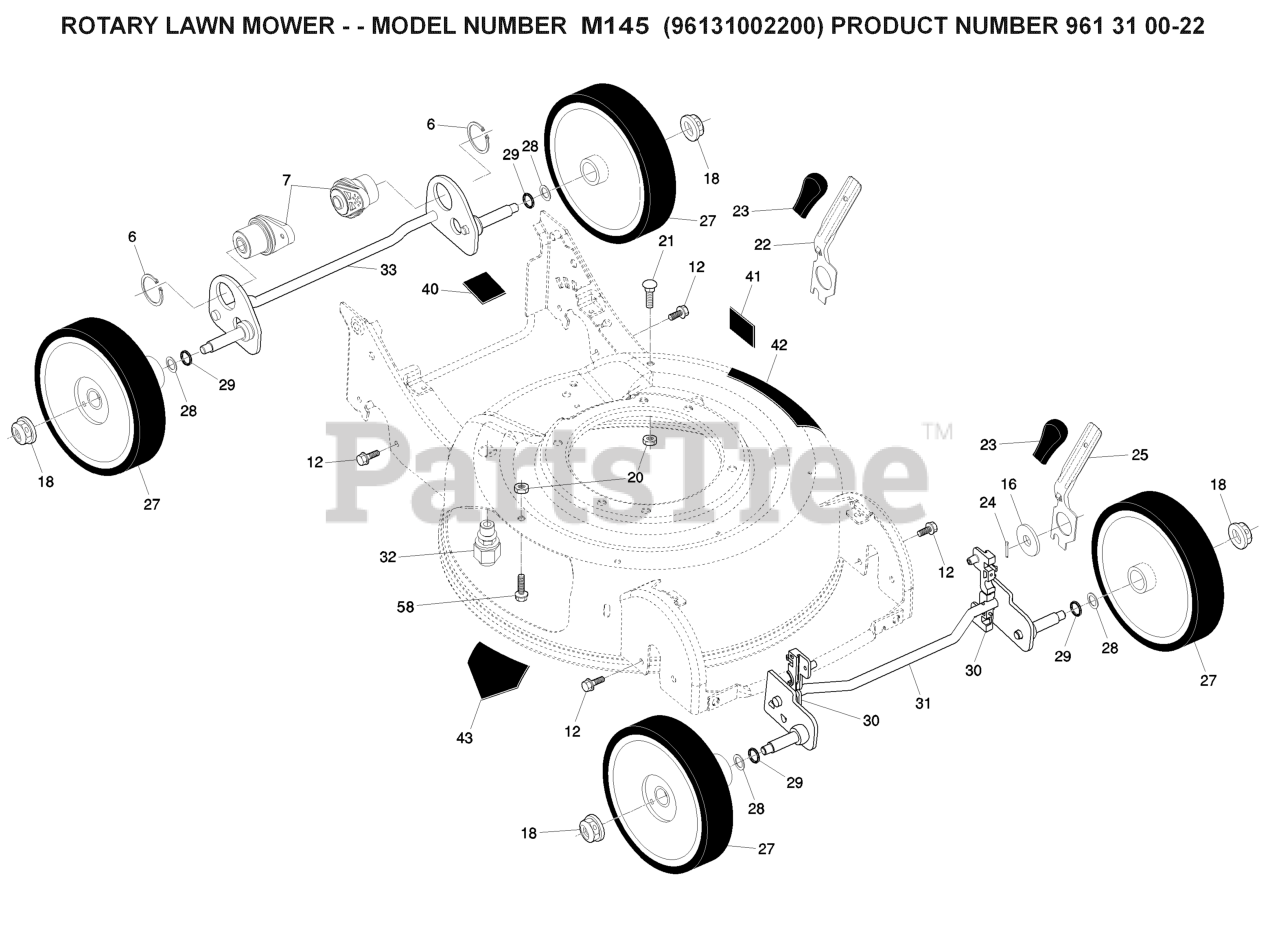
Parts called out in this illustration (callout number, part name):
6	RETAINING RING (2 2)(3 2)
18	NUT.HEX.FLANGE.3/8-16.LO(3 2)
20	NUT
21	BOLT.CARRIAGE.1/4-20 X 7/8
24	SPRING RETAINER
27	WHEEL & TIRES ASSY, FRONT
28	WASHER.FLAT.1/2
29	O-RING..070X.487.NEOPRENE
30	BUSHING.FRONT.TORQUE.S
33	AXLE.ASM.REAR.45CM.SP.BZP
43	DECAL.INTERNATIONL.CUTFINGER
